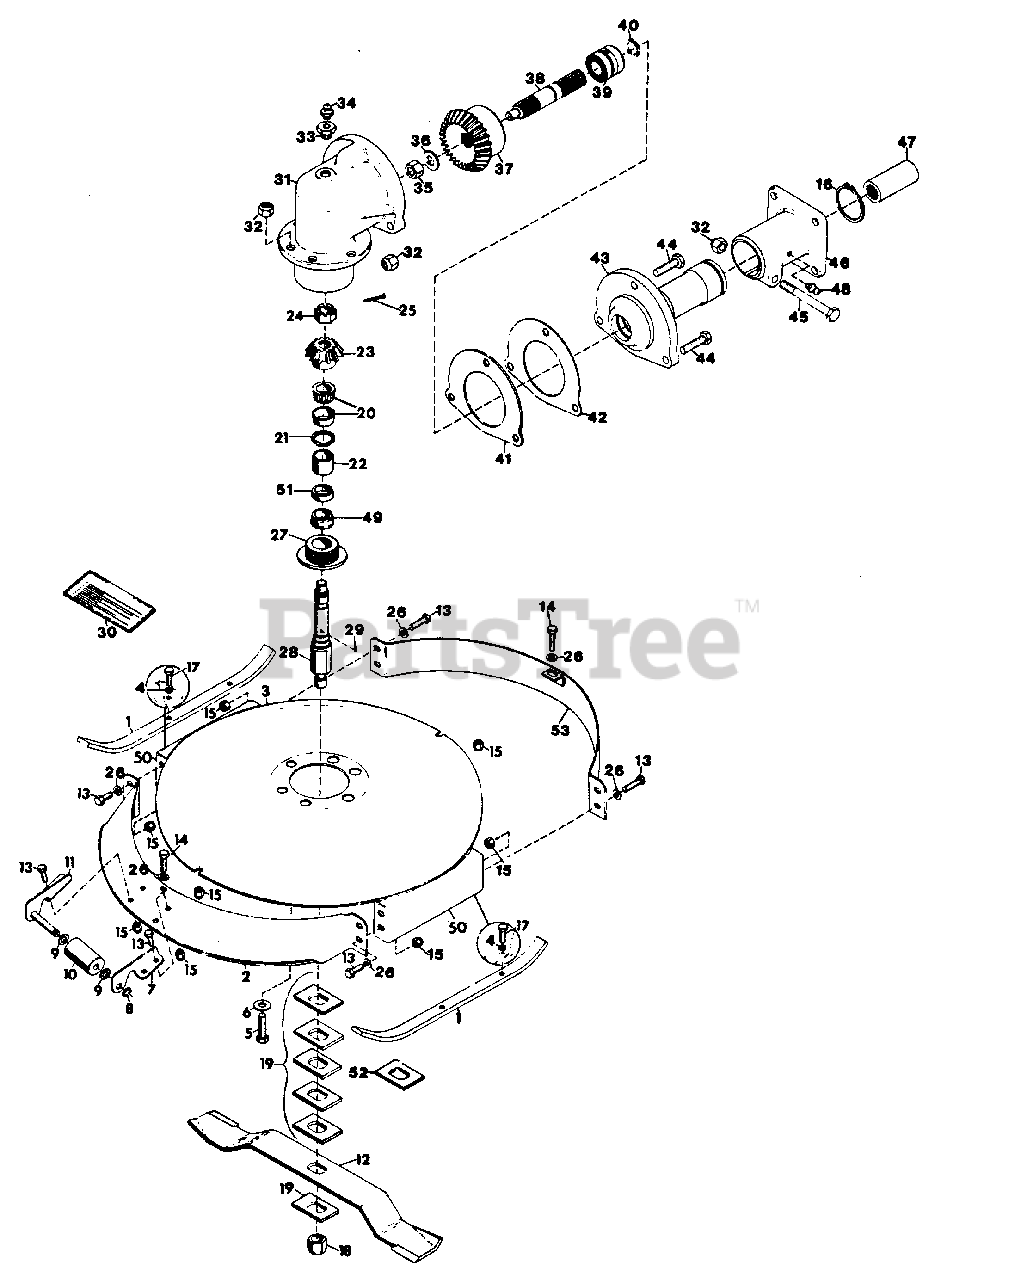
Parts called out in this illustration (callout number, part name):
1	SKID, ROTARY MOWER
2	FENDER, FRONT 30" MOWER
3	DECK, WELDMENT 30 IN.
4	WASHER LOCK 5/16 INT. TOOTH
5	BOLT, HEX 1/2-13 X 1.50
6	WASHER, FLAT 9/16 X 1-3/8 X .109
7	BRACKET, WHEEL L-H
8	E-RING
9	WASHER, FLAT .656 X 1.250 X .100
10	ROLLER, GAGE
11	WELDMENT, BRACKET
12	ROTARY MOWER BLADE 3/8"
13	BOLT, HEX 5/16-18 X .75
14	BOLT, HEX 5/16-18 X .875
15	NUT, LOCK 5/16-18 WASHER INSERT
16	RING, RETAINING
17	BOLT HEX 5/16-24 X 5/8
18	NUT LOCK 7/8-9 HEAVY THIN
19	SPACER, CUTTING HEIGHT 1/4"
20	ASSEMBLY, BEARING
21	RING, RETAINING
22	SPACER; 1.75 X 1.936 X 1.967
23	PINION BEVEL
24	NUT, HEX 5/8-18 SLOTTED
25	PIN COTTER 3/32 X 1-1/4
26	WASHER, FLAT .312 X .734 X .065
27	SEAL
28	SHAFT, ROTOR
29	KEY, WOODRUFF; .125 X .375
30	DECAL, DANGER
31	HOUSING, GEAR
32	NUT, LOCK; 1/2-13 WASHER INSERT
33	BUSHING, 1/2 REDUCING PIPE
34	FITTING, LUBE
35	NUT, LOCK; 5/8-18 HEX HD. TYPE-N
36	WASHER, FLAT .656 X 1.312 X .095
37	GEAR, BEVEL
38	SHAFT, DRIVE
39	ASSEMBLY, BEARING; 1.000 X 1.980 X 1.243
40	RING, RETAINING; .937 SHAFT
41	SHIM, .020
42	SHIM, .005
43	HOUSING, SHAFT
44	BOLT, HEX 1/2-13 X 1-3/4
45	BOLT, HEX 1/2-13 X 3.25
46	CASTING, SWIVEL
47	COUPLING
48	FITTING, LUBE; 1/4-28
49	CONE, BEARING
50	PANEL SKID
51	CUP, BEARING
52	SPACER, CUTTING HEIGHT 1/8"
53	WELDMENT, REAR FENDER
54	SUPPORT, DECK
